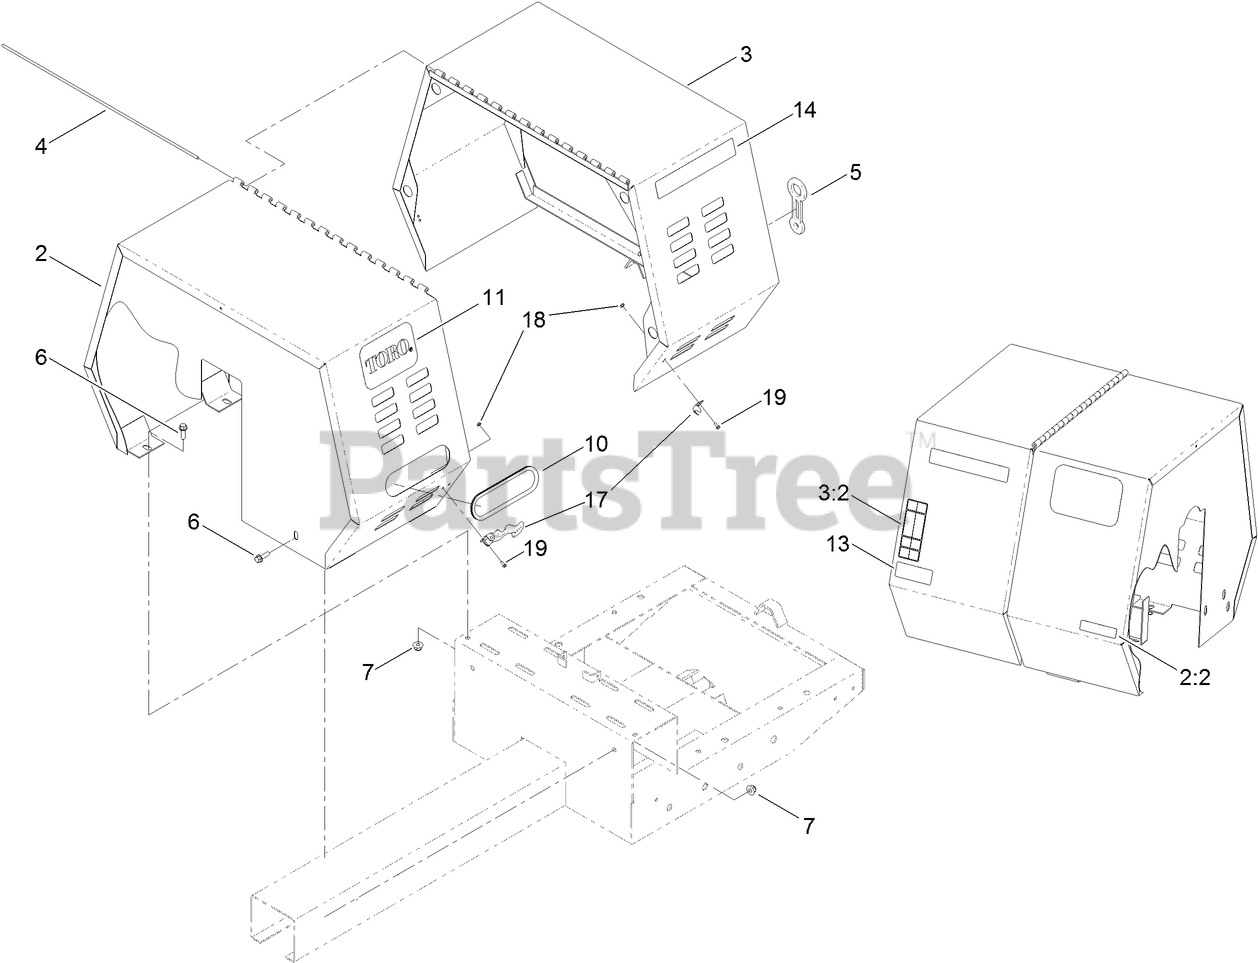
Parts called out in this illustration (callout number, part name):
2	STATIONARY COWL ASM
2:2	DECAL-ARRESTER, SPARK
3	MOVABLE COWL ASM
3:2	DECAL-WARNING
5	LATCH-RUBBER
6	SCREW-HHF
7	NUT-HF, NI
10	TRIM-LID
11	DECAL
14	DECAL-MM-12511H
17	LATCH-FLEX, DRAW
18	NUT-LOCK, NI
19	SCREW-HWH
